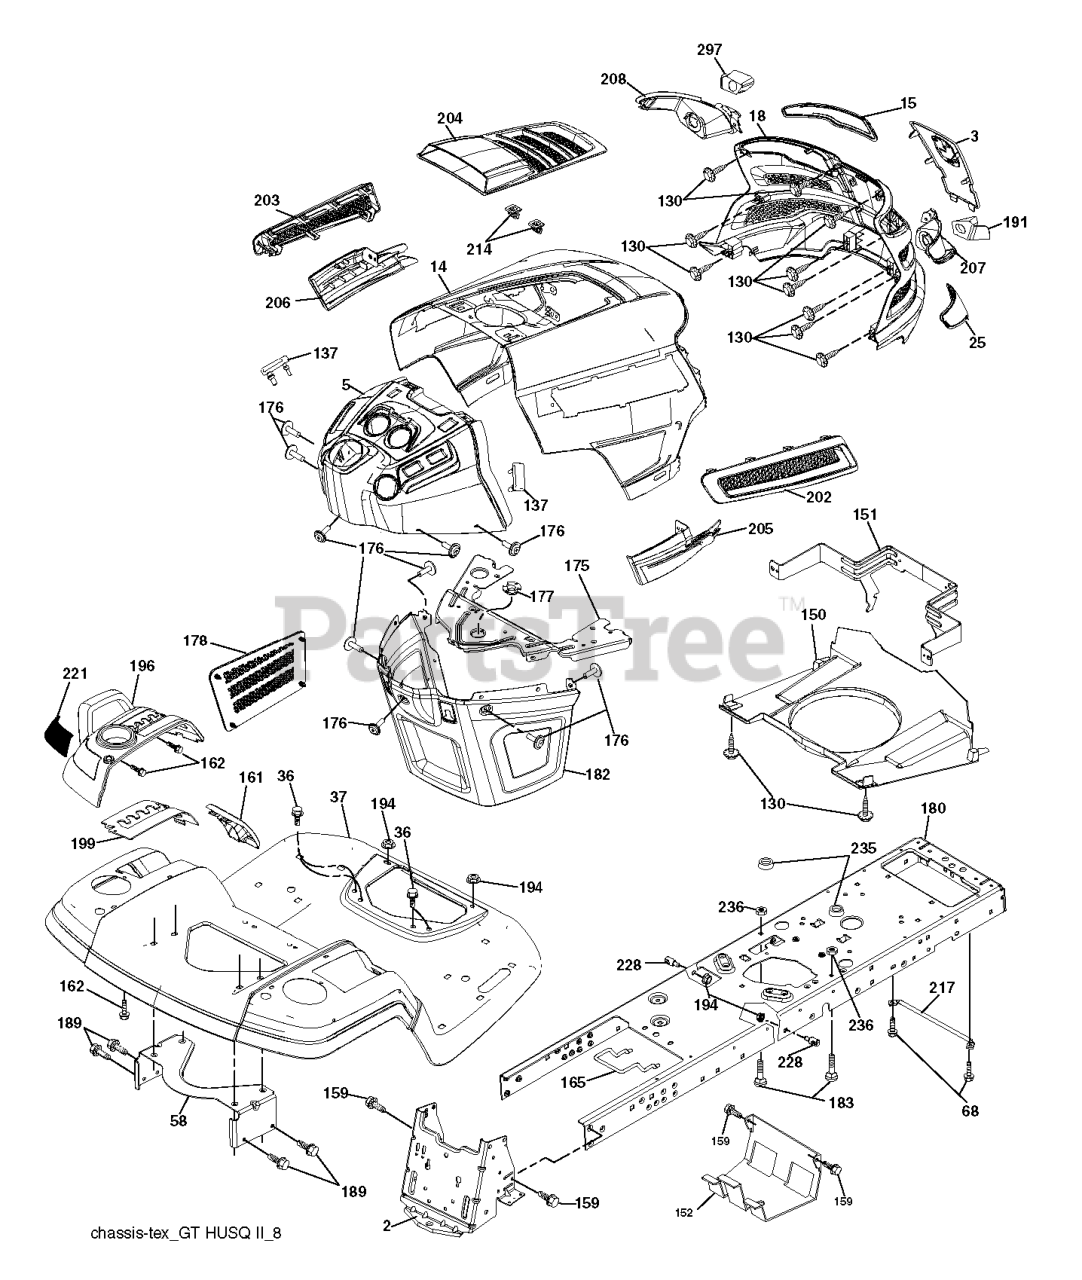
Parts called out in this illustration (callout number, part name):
2	DRAWBAR.STGT
3	APPLIQUE.SUBASM.GT.HUSQ.II
5	DASH.UPP.GT2.DR.PTO.ELEC.CHOKE
14	HOOD.ASM.HUSQVARNA.GT.TEX.422
15	LENS.HEADLIGHT.LH.GTII.2011
18	GRILLE.SUBASM.GT.HUSQ.II
25	LENS.HEADLIGHT.RH.GTII.2011
36	SCREW 5/16"
37	FENDER.PNT.TX.GT.CH/FW.ORANGE
58	BRKT.SUPPORT.FNDR/TANK
68	SCREW LT
130	SCREW.#10 X 0.750.BOS
137	BUMPER DASH
150	AIR.DUCT.GTV.BLACK
151	BRACKET.PIVOT.HOOD.GT.HUSQ.II
152	SHIELD.BROWNING.PNT.GT.V2
159	SCREW, 3/8-16X3/4
161	CONSOLE.WINDOW.FUEL.HUSQ.GT
162	SCREW.HI-LO.CONSOLE
165	SUPPORT.TANK.REAR.B/TE
175	PLATE.CROSSMEMBER.HUSQ
176	SCREW.#10-24X5/8.RN.QU
177	BUSHING, STEERING
178	CARGO.ASM.NET.TXGT.W/C
180	CHASSIS.STAMPING.LT/GT
182	DASH.LOWER.COMMON.12V.ADAPTOR
183	BOLT.5/16-18X1-1/4 FULL THD
189	SCREW
191	INSERT.REFLECTIVE.RH.HUSQ.GTII
194	NUT LOCK HEX FLANGE 5/16-18
196	CONSOLE.ASM.DECKLIFT.HUSQGT.DL
199	PLATE.DECK.LIFT.HUSQVARNA.GT
202	VENT.SIDE.RH.GT.HUSQ.II.
203	VENT.SIDE.LH.GT.HUSQ.II.498
204	VENT.TOP.HUSQ.GT2
205	SIDE.TRIM.RH.GT.HUSQ.II
206	SIDE.TRIM.LH.GT.HUSQ.II.GRAY
207	BEZEL LIGHT.RH.GT.II.MYLAR
208	BEZEL LIGHT.LH.GT.II.MYLAR
214	CLIP.RETAINER.TINNER.
217	ROD.PIVOT.HOOD
221	REFLECTOR.LH.TEX GT HU
228	STUD.FASTNER.W/ANTI-ROTATE
235	SPACER FENDER
236	NUT.CENTERLOCK.5/16-
297	INSERT.REFLECTIVE.LH.HUSQ.GTII
